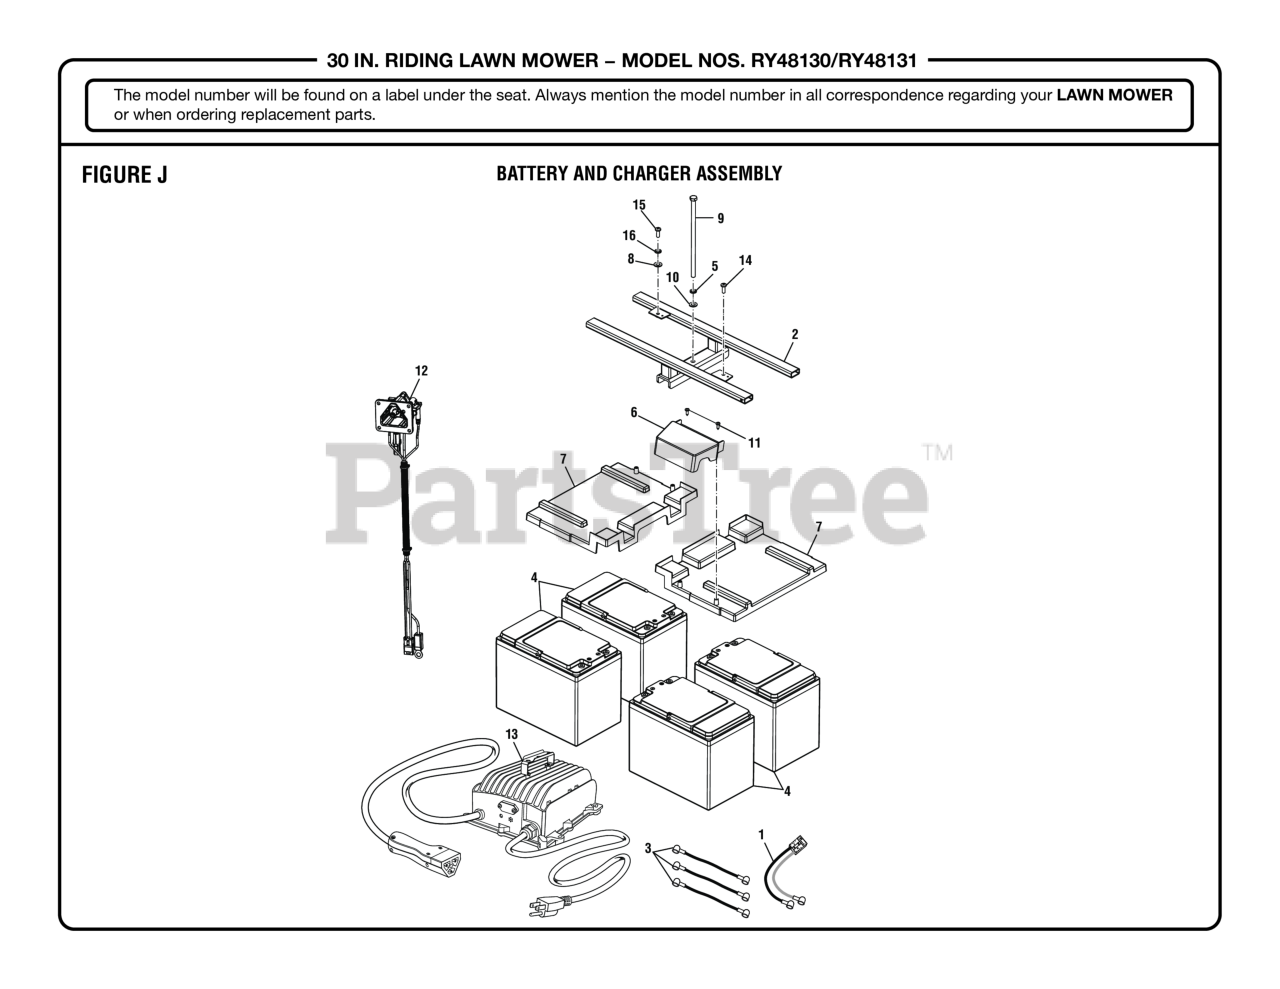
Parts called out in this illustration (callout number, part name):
1	Battery Cable 2
2	Battery Tie Down
3	Battery Cable 1
5	Lock Washer (OD9.8 x ID8.5 x 5t)
6	Main Relay Cover
7	Battery Cover
8	Washer (OD7 x ID3.2 x 0.6t) (For Beeper Q)
9	Bolt (M8 x 180 mm, Hex Hd.)
10	Washer (OD16 x ID8.4 x 1.6t)
11	Screw (ST4.2 x 13 mm)
12	Charger Receptacle
14	SCREW,PPHMS, M5 X 0.8 X 16 - STEEL,
15	Screw (M3 x 20)
16	WASHER, LOCK SPRING, 3MM, ZINC BLACK
